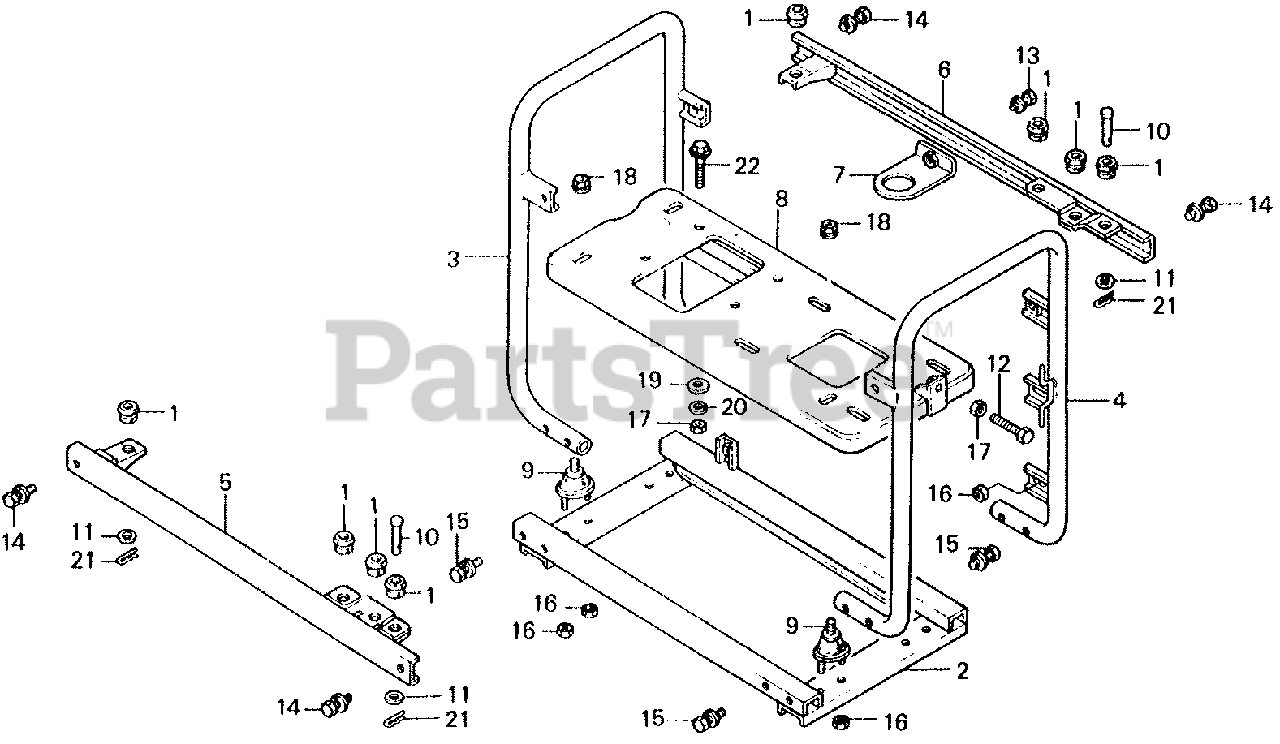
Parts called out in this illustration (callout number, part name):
1	RUBBER, TANK CUSHION
2	BED, FRAME
3	FRAME, L. SIDE
4	FRAME, R. SIDE
5	FRAME, FR. (UPPER)
6	FRAME, RR. (UPPER)
7	STOPPER, ENGINE
8	BED, ENGINE
9	RUBBER (LOWER) (NOT AVAILABLE)
10	PIN, CONTROL BOX SETTING
11	WASHER, FLAT (20MM)
12	BOLT, HEX. (8X40)
13	BOLT-WASHER (6X12)
13	BOLT, FLANGE (6X12)
14	BOLT-WASHER (8X16)
15	BOLT-WASHER (8X20)
16	NUT, HEX. (6MM)
17	NUT, HEX. (8MM)
18	NUT, FLANGE (8MM)
19	WASHER, PLAIN (8MM)
20	WASHER, SPRING (8MM)
21	PIN, LOCK (8MM)
22	BOLT, FLANGE (8X40)
